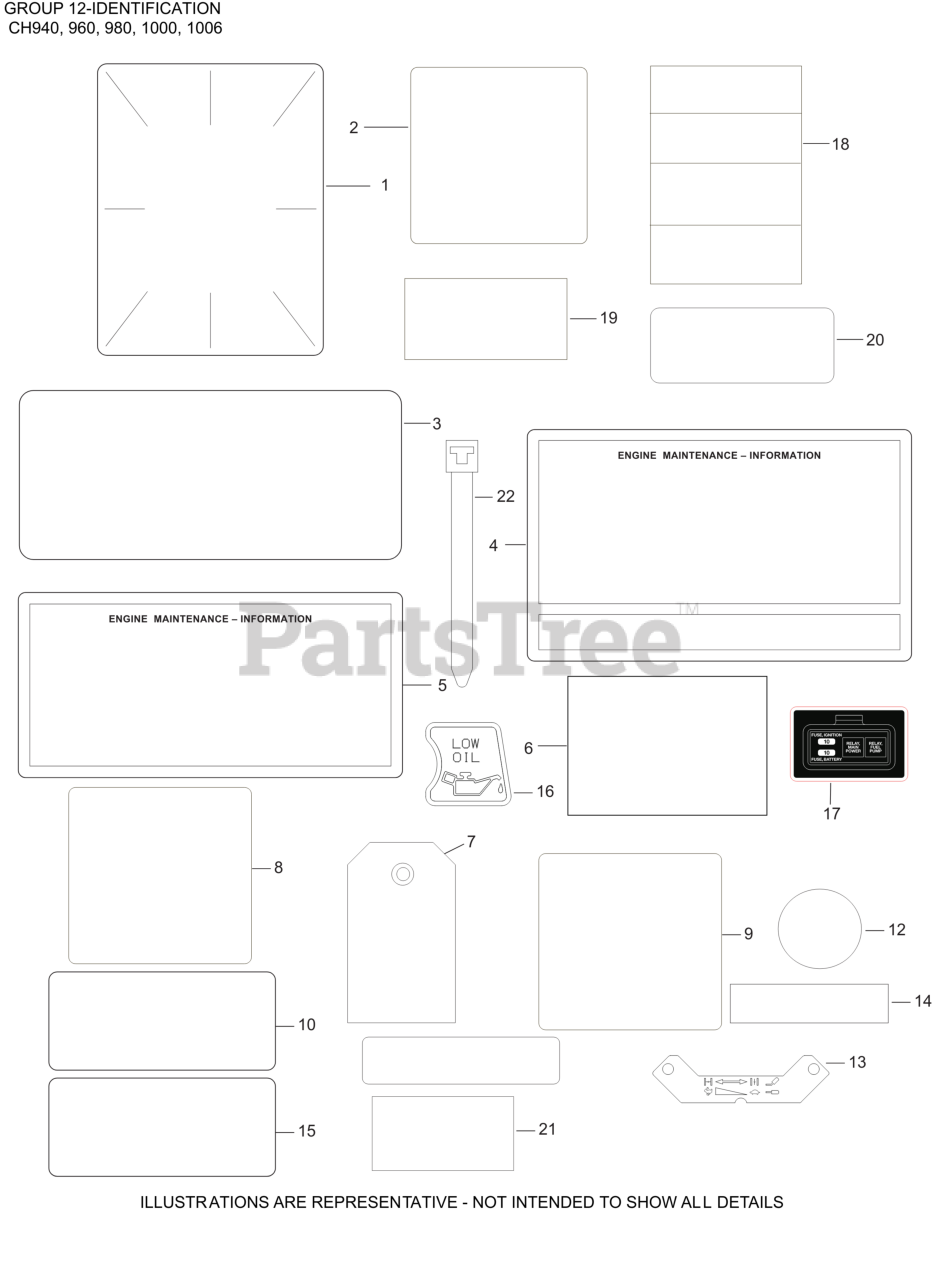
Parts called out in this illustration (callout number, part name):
1	LABEL, CLEAR LAMINATION
20	DECAL, SYNTHETIC OIL
21	DECAL, USA
